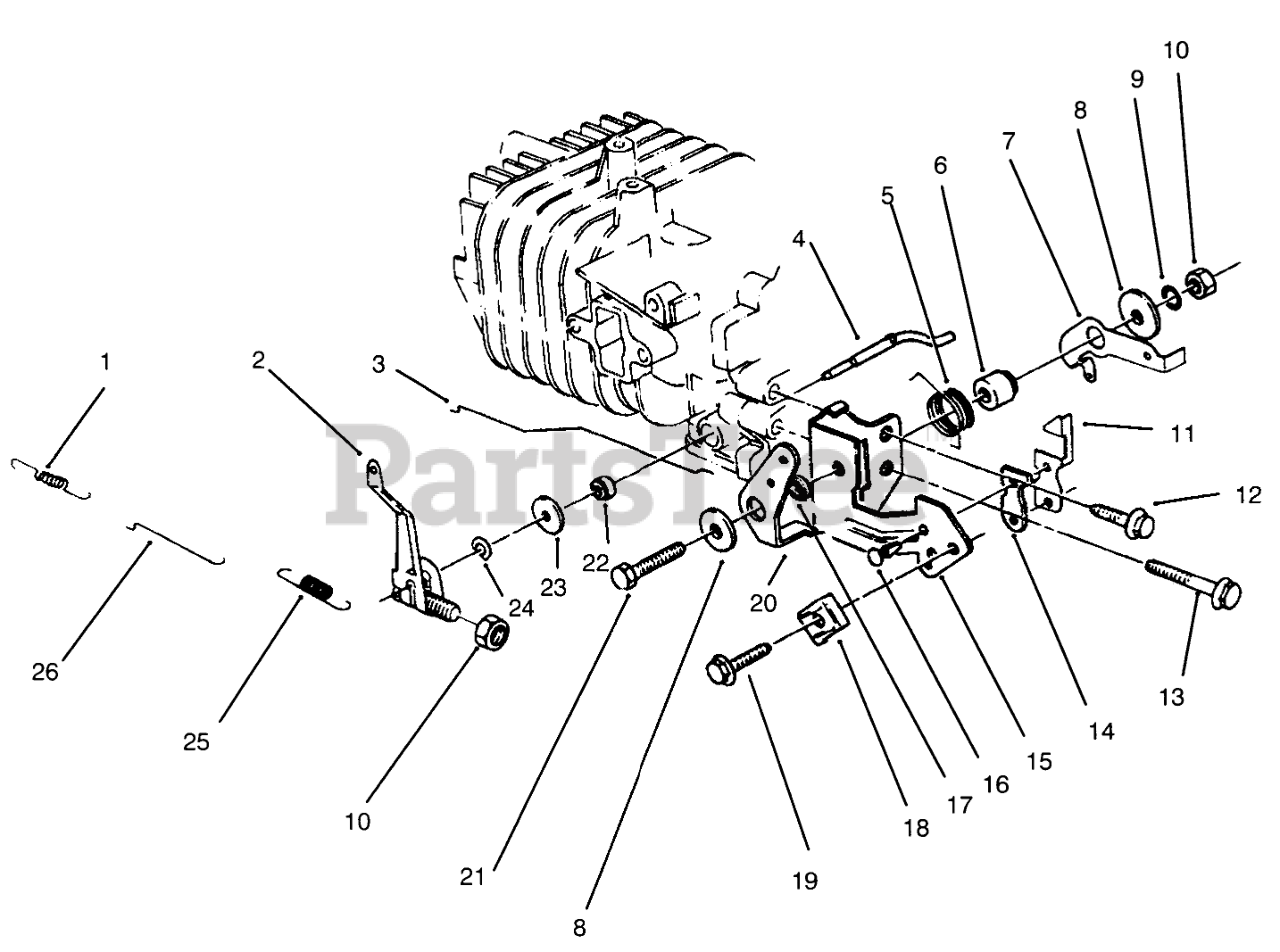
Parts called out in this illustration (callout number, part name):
1	SPRING
2	ARM-GOVERNOR
3	ROD-CHOKE
4	SHAFT
5	SPRING-CHOKE LEVER
6	Gov Lever Spacer
7	LEVER-SPRING, GOVERNOR
8	WASHER
9	LOCKWASHER
11	TERMINAL-KILL SWITCH
14	INSULATOR-KILL SWITCH
15	BRACKET-THROTTLE, CONTROL
16	RIVET
17	SPACER-CHOKE LEVER
18	CLAMP
20	LEVER-CONTROL, CHOKE
22	SEAL-OIL
23	WASHER
24	E-RING
25	SPRING-GOVERNOR
26	ROD-CARBURETOR
